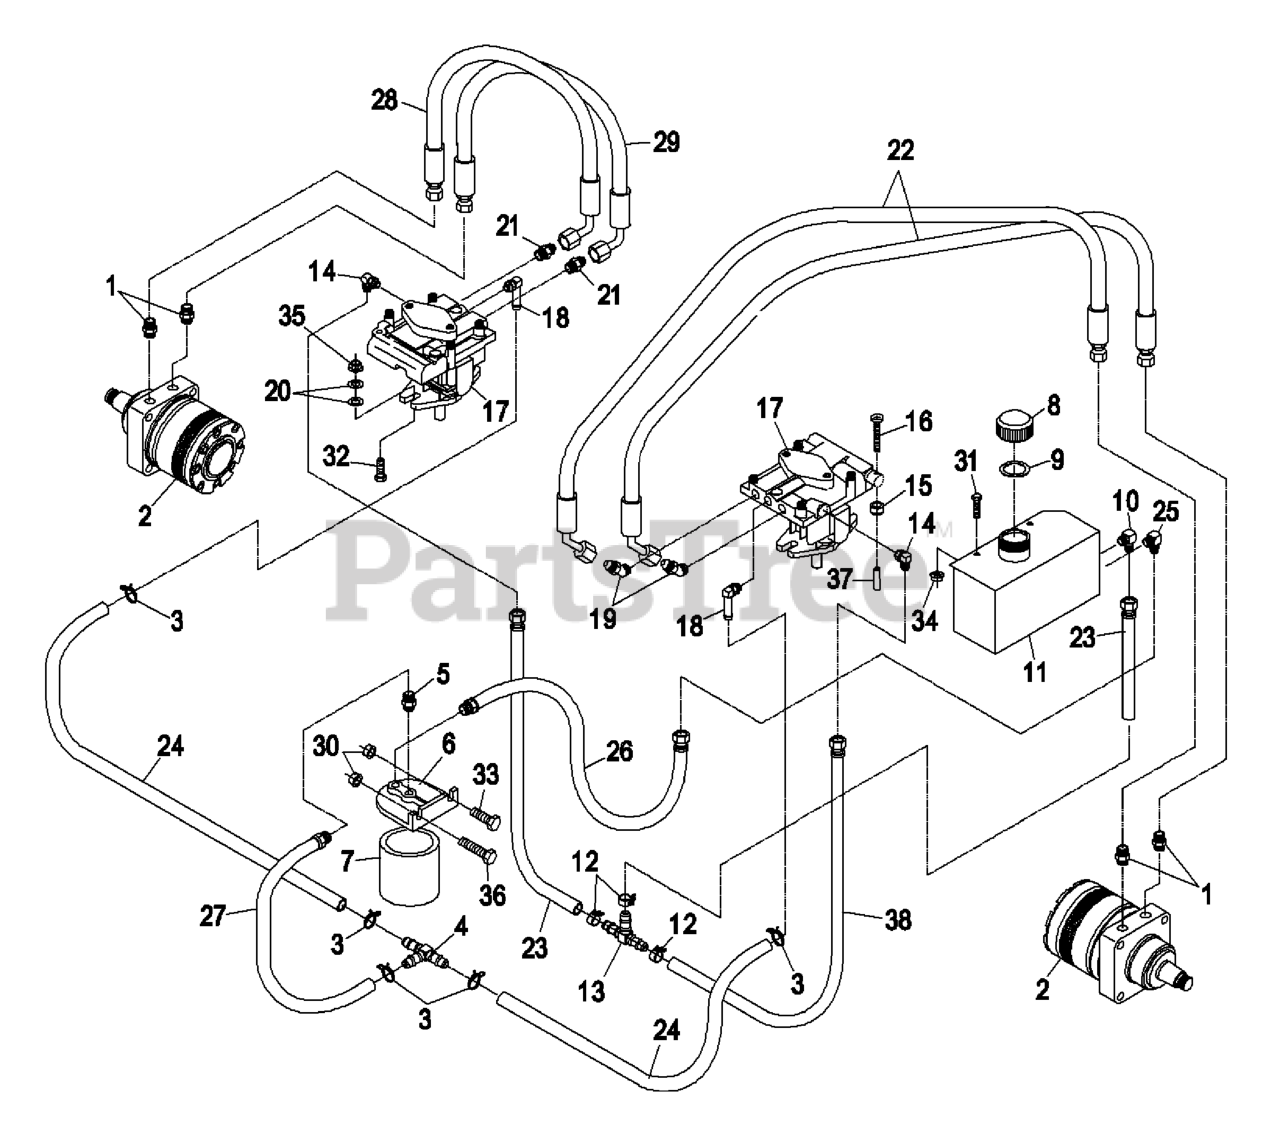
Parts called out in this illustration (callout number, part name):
1	FITTING-STRAIGHT
2	HYD MOTOR ASM
3	CLAMP-HOSE
4	FITTING-TEE, HOSE
5	FITTING-STRAIGHT
9	GASKET-CAP, TANK
10	FITTING-ELBOW
12	CLAMP-HOSE
13	FITTING-TEE, HOSE
14	FITTING-90 DEG
15	NUT-LOCK, NI
18	FITTING
19	FITTING-HYD, 45 DEG
20	WASHER-FLAT
21	FITTING-STRAIGHT
22	HOSE,HIGH PRESSURE
23	ASM,HOSE CASE DRAIN
24	HOSE,LO PRESSURE
25	FITTING-ELBOW
26	ASM,HOSE LO PRESSURE
27	ASM,HOSE CHARGE LINE
29	HOSE-PRESSURE, HIGH
31	SCREW-HH
32	SCREW-HH
33	SCREW-HH
35	NUT-HHF, WHIZ
36	SCREW-HH
37	GRIP-VALVE, DUMP
38	HOSE ASM
